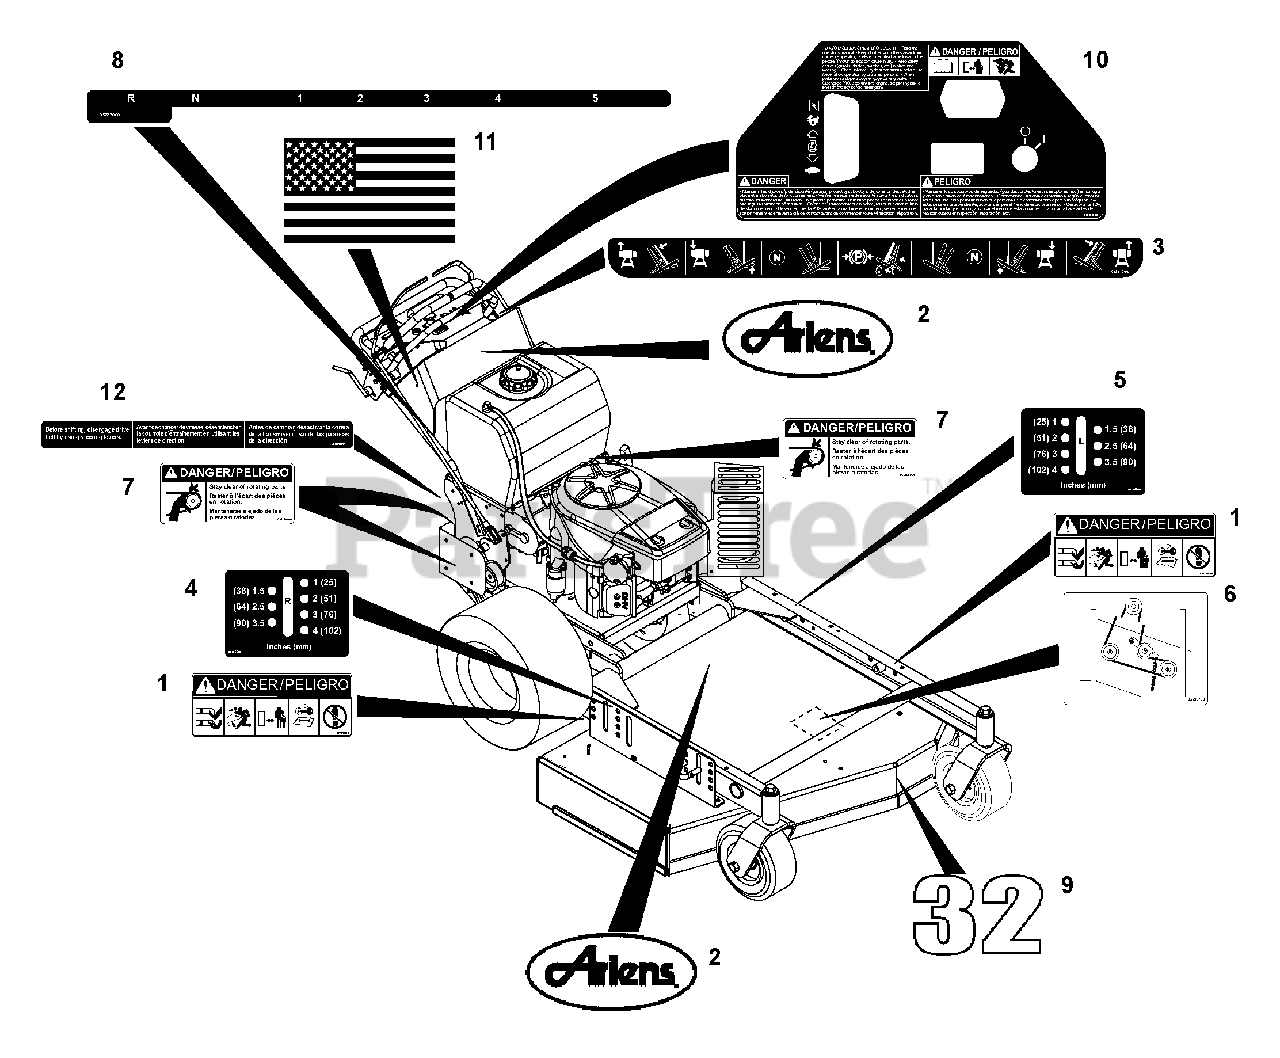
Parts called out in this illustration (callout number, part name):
1	DECAL, MOWER PAN DANGER
2	DECAL, ARIENS
3	DECAL-STEER LEVERS-GEAR-ERGO
4	DECAL-HEIGHT OF CUT-FIXED - RH
5	DECAL-HEIGHT OF CUT-FIXED - LH
6	DECAL-BELT DIAGRAM-2 SPINDLE
7	DECAL-DANGER-BELT ROTATING
8	DECAL-SHIFT LEVER
9	DECAL, 32
10	DECAL-CONTROL GR13-ERGO
11	DECAL, AMERICAN FLAG
12	DECAL - DECLUTCH - GEAR
